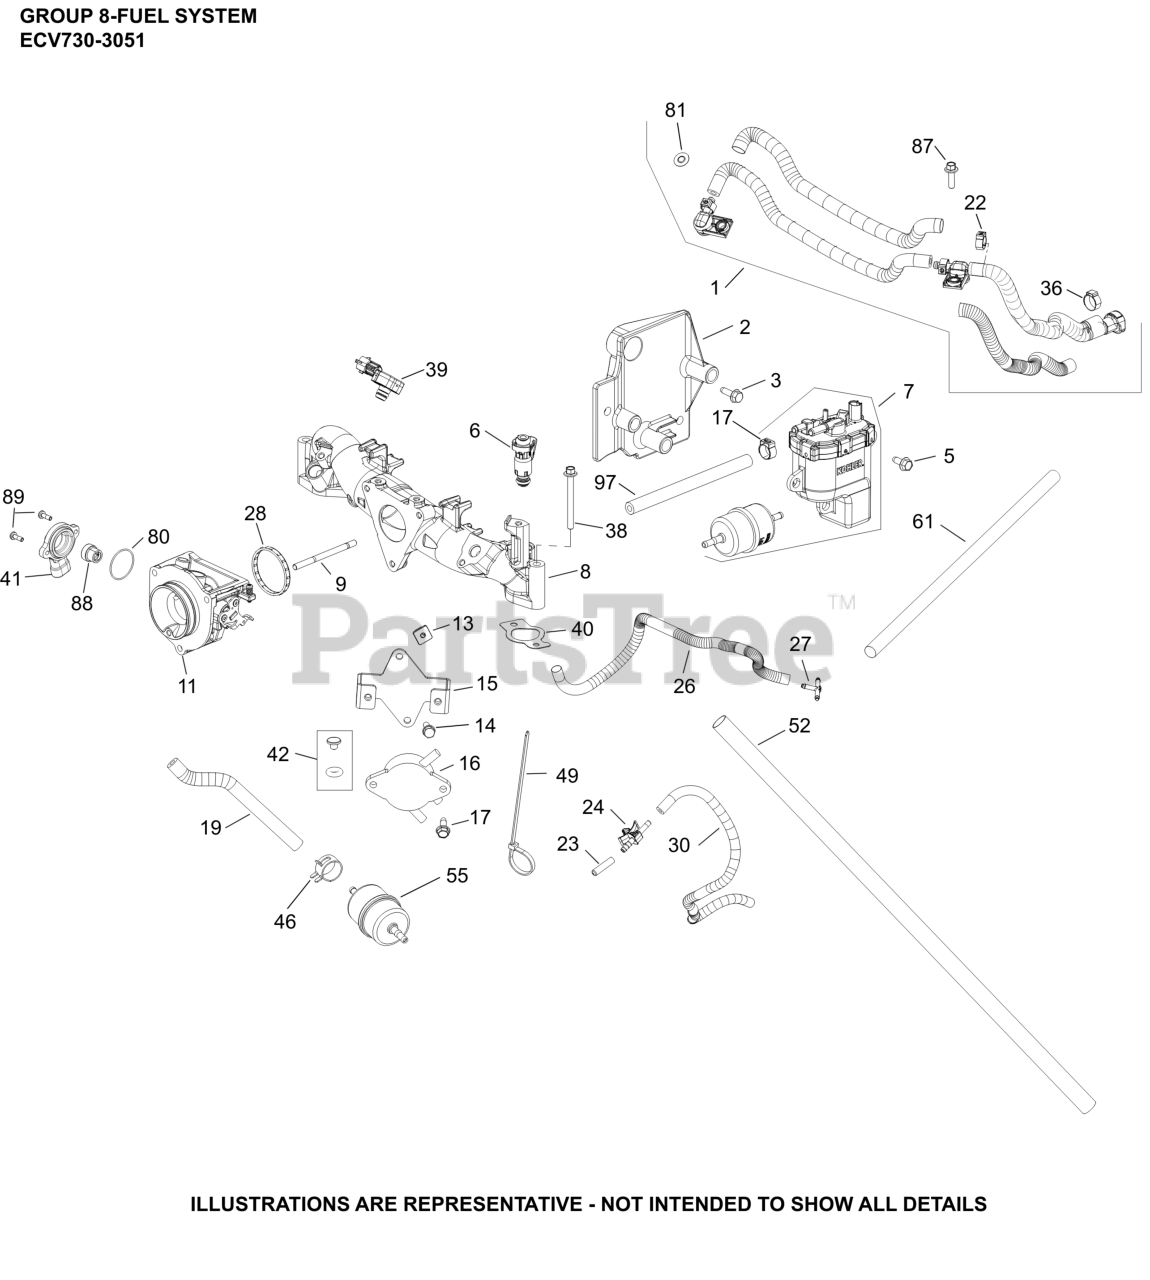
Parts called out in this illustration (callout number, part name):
1	FUEL HOSE ASSY(ECV,FCV,EZT,EKT,PCH,PCV)
2	KIT,BAFFLE, FUEL MODULE
3	SCREW, THREAD FORMING
5	SCREW, FLG M6X1.0X16
6	INJECTOR, FUEL
7	KIT, FUEL PUMP MODULE
8	KIT, MANIFOLD
9	STUD,M6X1.0X84
11	BODY, THROTTLE ASM W/ PIN (30)
13	NUT, PLASTIC - BLACK
14	SCREW, HEX HEAD
15	BRACKET, FUEL PUMP MOUNTING
16	PUMP, FUEL
17	SCREW, THREAD FORMING
19	HOSE,LW PERM.FUEL 24.00"-USE 25 111 81-S
22	CLAMP, OETIKER
23	CAP, MASKING
24	CONNECTOR, EVAPORATIVE
26	SLEEVE, ANTI-ABRASION
27	TEE CONNECTOR
28	O-RING, THROTTLE BODY
30	HOSE, EVAPORATIVE (15.0)
36	CLAMP, HOSE
38	SCREW, FLG M6X1.0X60
39	SENSOR, T-MAP
40	KIT, INTAKE MANIFOLD GASKET
41	SENSOR, THROTTLE POSITION
42	KIT, FUEL INJECTOR O-RING
46	SPRING CLAMP, HOSE
52	SLEEVE, HEAT REFLECTIVE
55	FILTER, FUEL
61	SLEEVE, ANTI ABRASION -USE 25 431 12-S
80	O-RING, TPS SENSOR
81	CLIP, RETAINER
87	SCREW, FLG M6x1.0x20
88	MAGNET ASSEMBLY, TPS
97	HOSE, FUEL LOW-PERMEATION
NI	SLEEVE, ANTI ABRASION-USE 25 431 12-S
